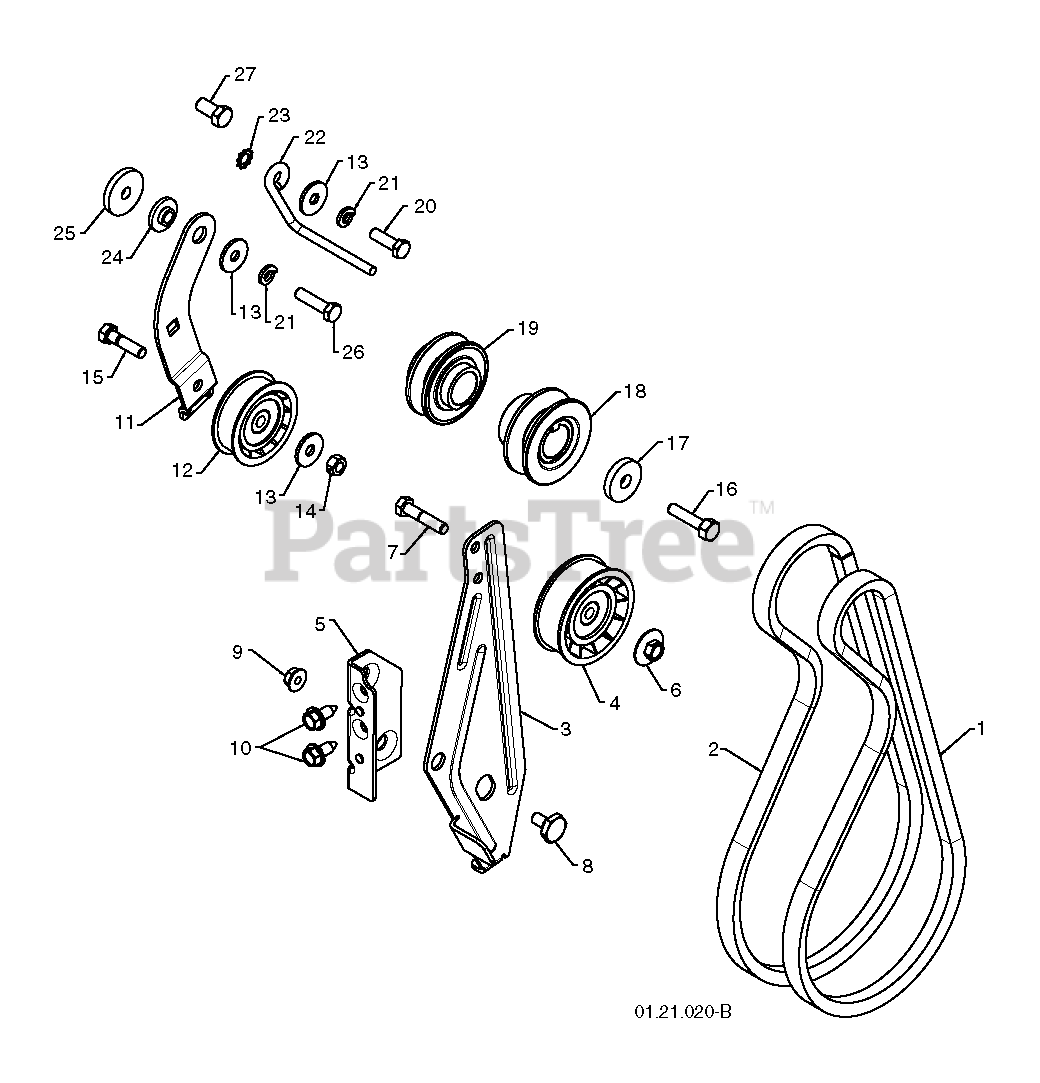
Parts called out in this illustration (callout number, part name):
1	V-BELT.IMPELLER
2	TRACTION BELT
3	RP ARM.IDLER.BRAKE.
4	PULLEY.W/SPACER.2.75
5	RP BRACKET.IDLER.PIVOT
6	NUT.FLANGE.HEX.5/16X18.BLACK
7	HEX BOLT
8	BOLT.SHOULDER.1/2X12
9	NUT.LOCK.5/16-18
10	BOLT.5/16HEX.WHS.HD
12	PULLEY.W/SPACER.2.25
13	STEEL WASHER
14	NUT.71038.31-18.HEX.NYLOCK
15	BOLT.5/16-18X1-1/4 FULL.THREAD
16	SCREW, HEX HD 3/8-24 X 1-3/8
17	WASHER.400X1.25X5.
18	PULLEY ENG IMPELLER
19	PULLEY.ASM.ENG.TRACTION.1.00
21	LOCKWASHER
22	Belt Guide, RH
24	BUSHING, IDLER PIVOT
25	WASHER.FLAT.34X1.38X22
26	CAPSCREW.HEXHD.5/16X1.25.
27	SCREW.3/8-16 X .750
